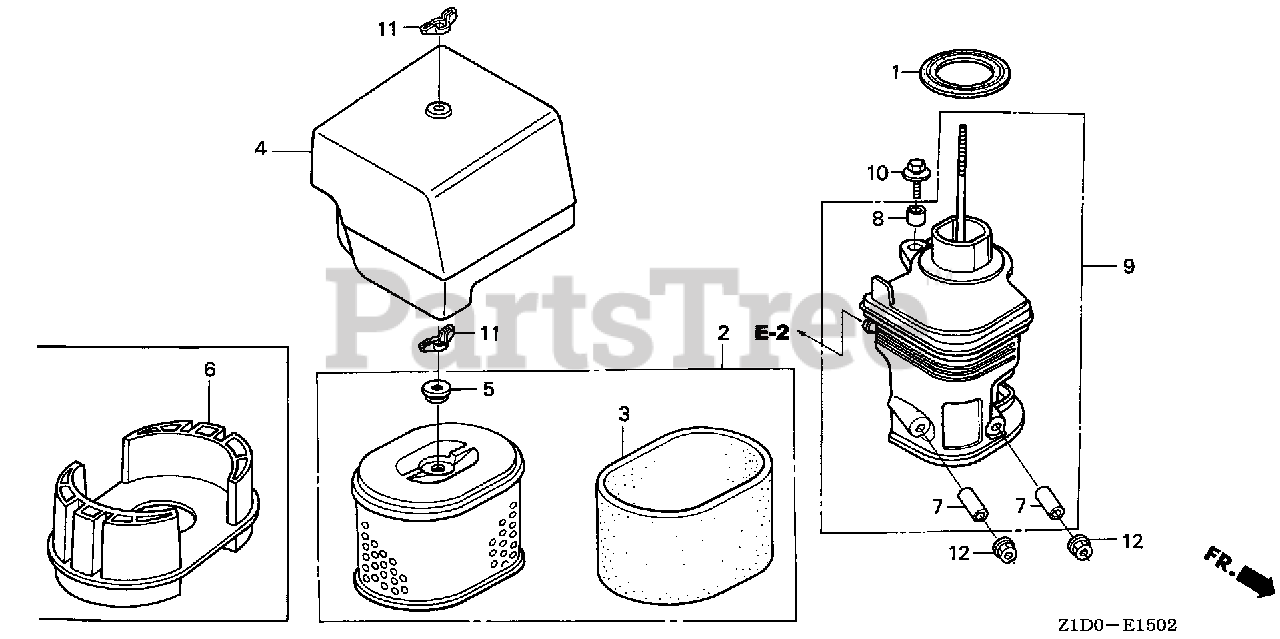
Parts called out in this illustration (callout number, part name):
1	GASKET, ELBOW
2	ELEMENT, AIR CLEANER (DUAL)
3	FILTER (OUTER)
4	COVER, AIR CLEANER
5	GROMMET, AIR CLEANER
7	COLLAR, AIR CLEANER
8	COLLAR B, AIR CLEANER
9	ELBOW, AIR CLEANER
9	ELBOW COMP, AIR/C
10	BOLT-WASHER (6X22)
11	NUT, TOOL BOX SETTING
12	NUT, FLANGE (6MM)
